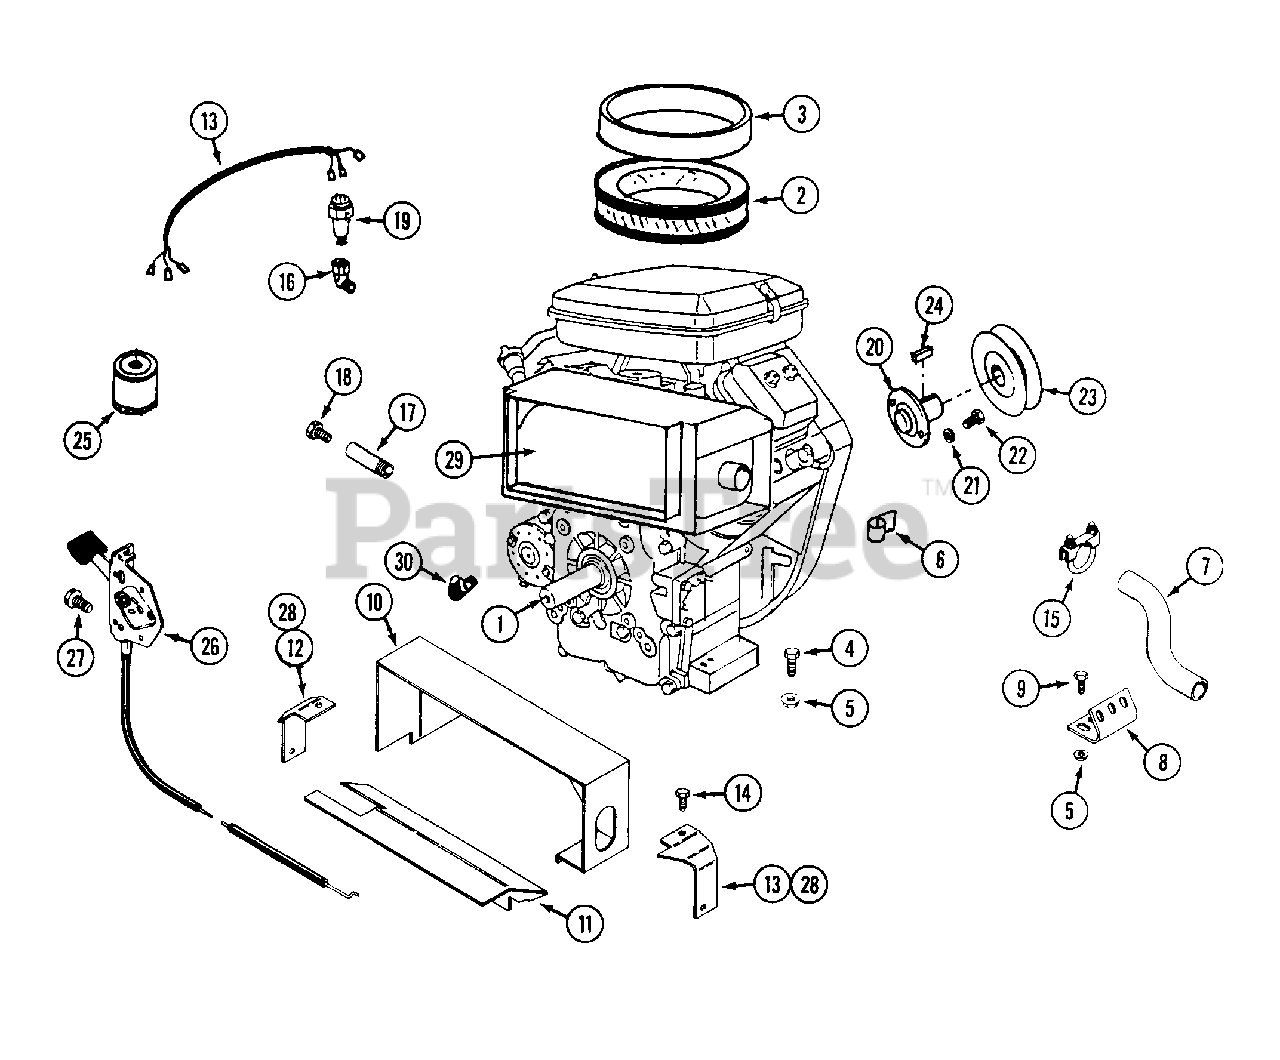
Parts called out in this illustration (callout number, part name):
1	ENGINE - Briggs & Stratton model 350447, type 0139 (18 hp)
2	ELEMENT - air cleaner
3	PRE-CLEANER
4	BOLT - 5/16" - 18 x 1-1/4"
5	NUT - 5/16" - 18 flange lock
6	CLIP - "J"
7	PIPE - exhaust
8	BRACKET - exhaust pipe
9	BOLT - 5/16" - 18 x 1"
10	DUCT - muffler, upper
11	DUCT - bottom
12	SUPPORT - duct, front
13	SUPPORT - duct, rear
14	SCREW - M6 x 10
15	CLAMP - exhaust
16	FITTING - street elbow, 1/4" NPT 45°.
17	NIPPLE - pipe 3.5"
18	PLUG - 1/2" - 20
19	UNIT - oil sending
21	LOCKWASHER - 3/8"
22	BOLT - 3/8" - 16 x 1"
23	PULLEY - engine (use 83-55 set screw)
24	KEY - 1/4" X 1 /4" x 1"
25	FILTER - oil
26	CABLE - throttle
27	SCREW - #12 x 1/2"
28	BAFFLE - duct
30	COVER - terminal, starter
